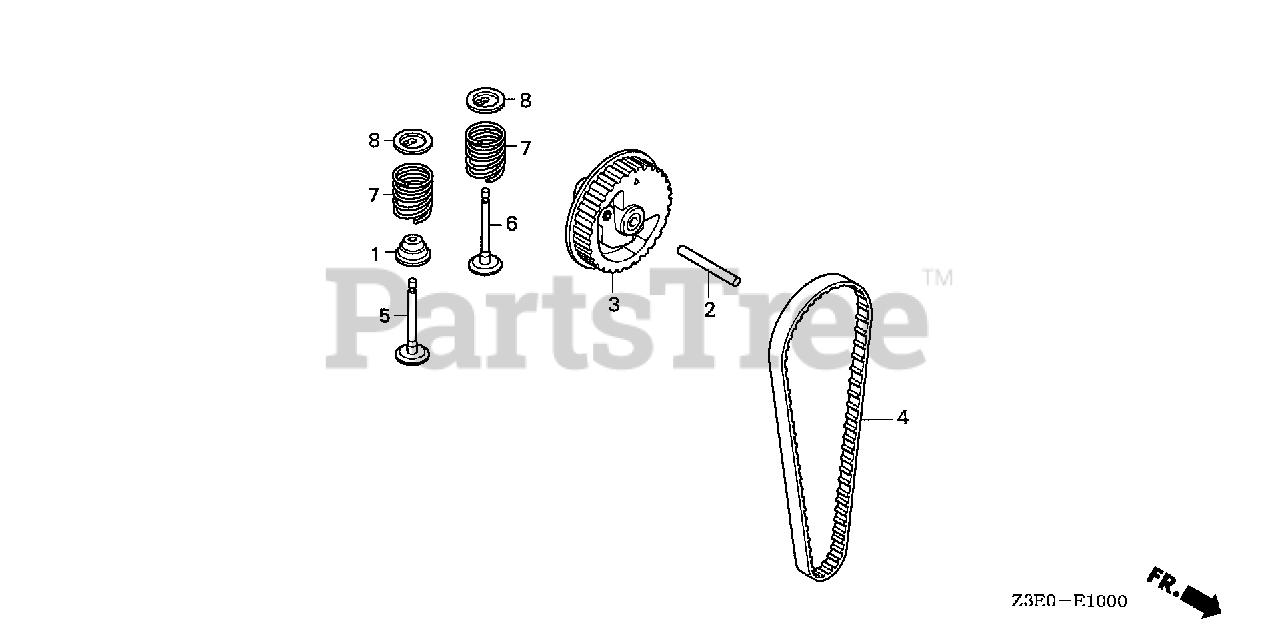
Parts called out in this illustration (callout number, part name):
1	SEAL, VALVE STEM
2	ROLLER (4X29.8)
3	PULLEY, CAMSHAFT
4	BELT, TIMING (71ZU6 G-300)
4	BELT, TIMING (71ZU5 G-310)
5	VALVE, IN. (EI)
6	VALVE, EX. (EE)
7	SPRING, VALVE
8	RETAINER, VALVE SPRING
